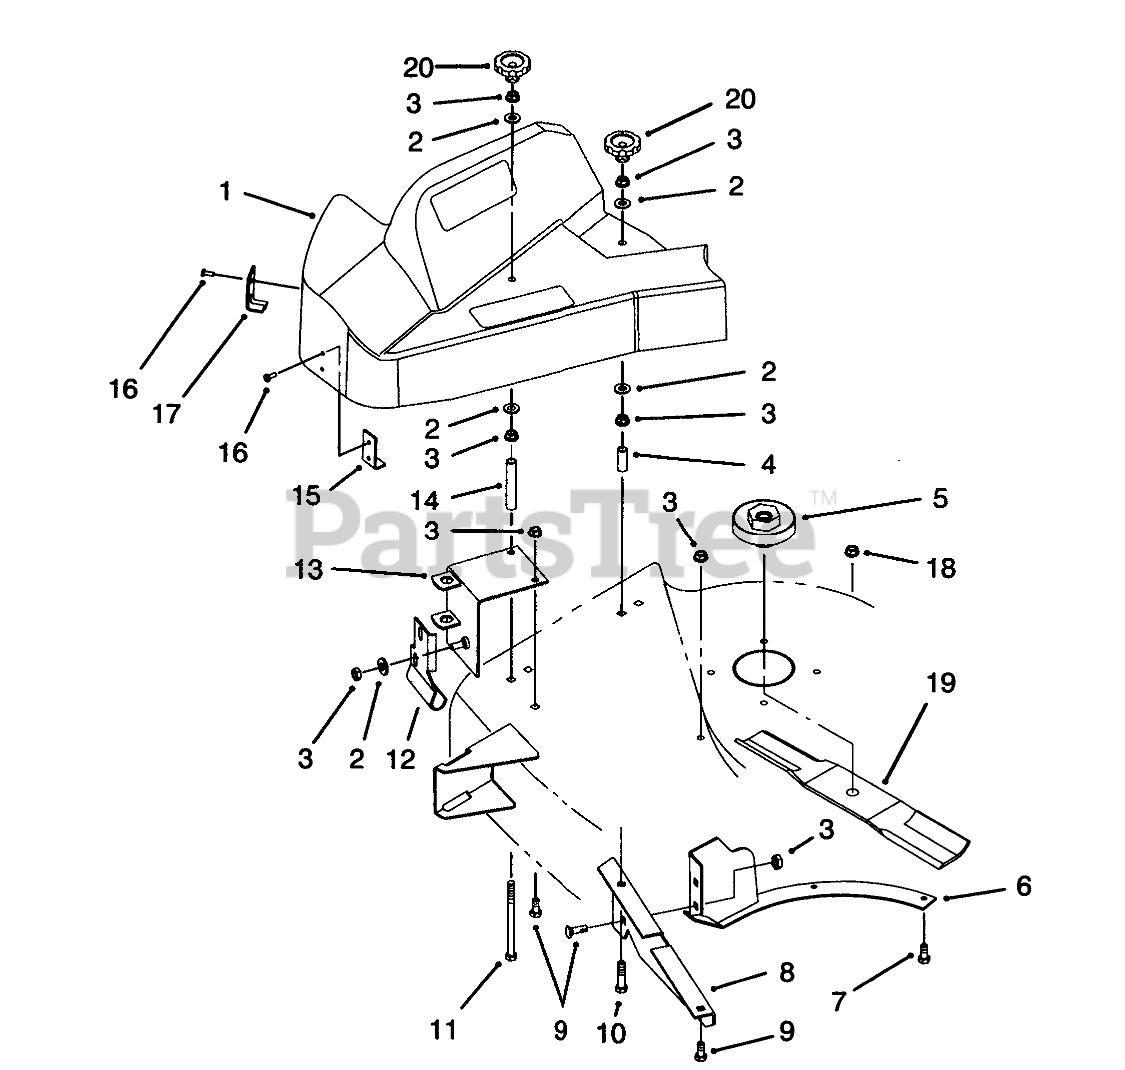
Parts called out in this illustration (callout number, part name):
1	Shield-Belt (Incl. Ref. #15-17)
2	WASHER-PLAIN
3	NUT-LOCK, NI
4	TUBE-LATCH
5	PULLEY
6	BAGGING RING RH-WELDED B
7	SCREW-HH
8	Baffle-Rear
9	SCREW-CARR
10	SCREW-CARR
11	SCREW-CARR
12	BRACKET - PIVOT BLACK
13	WA - PIVOT BRACKET
14	TUBE-SPACER
15	BRACKET-SUPPORT, SHIELD
16	RIVET-POP
17	BRACKET-SUPPORT, SHIELD
18	NUT-LOCK, NI
19	Blade
